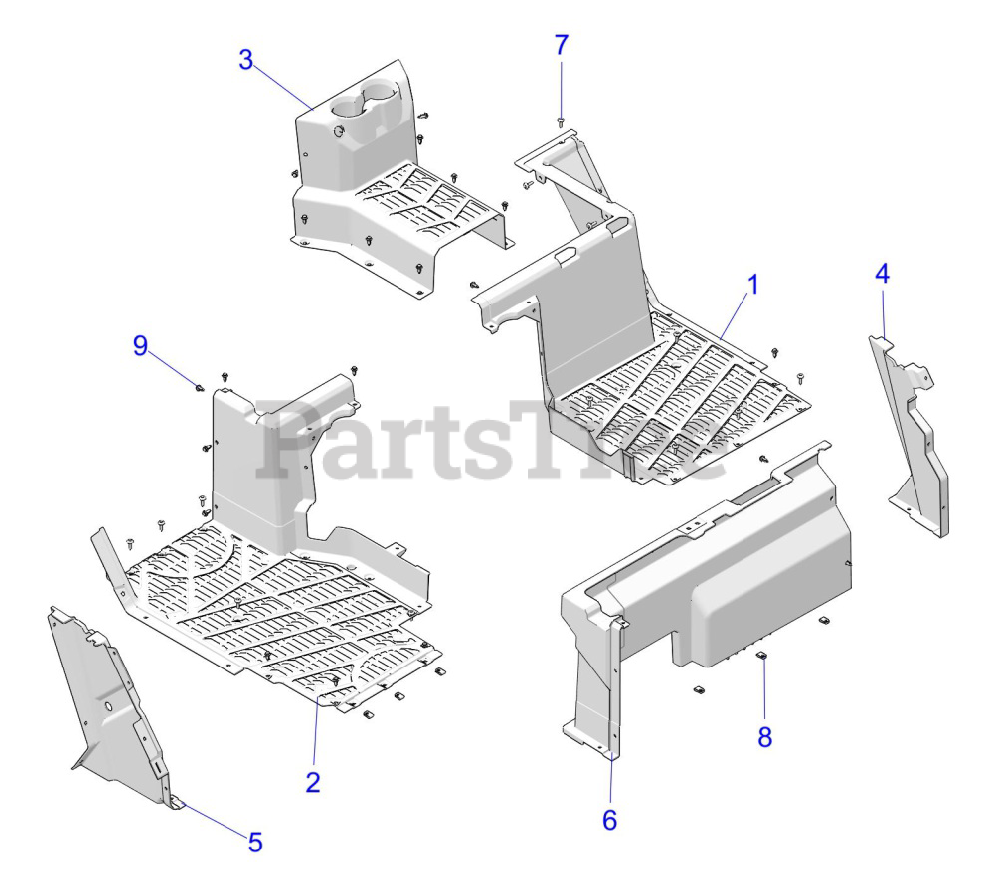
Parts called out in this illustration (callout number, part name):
1	FLOOR-REAR-LH-BLK
2	FLOOR- REAR- RH- BLK
3	COVER-TUNNEL FLOOR-REAR-BLK
4	COVER-INNER ROCKER-LH-BLK
5	COVER-INNER ROCKER-RH-BLK
6	COVER-REAR CLOSE OFF-BLK
7	SCR-TXTH-M6X1.0X25 RIE
8	NUT-M6-1.0- U-TYPE (2.5-3.8)
9	RIVET-TUFLOK-.315-.325X.787 (5
